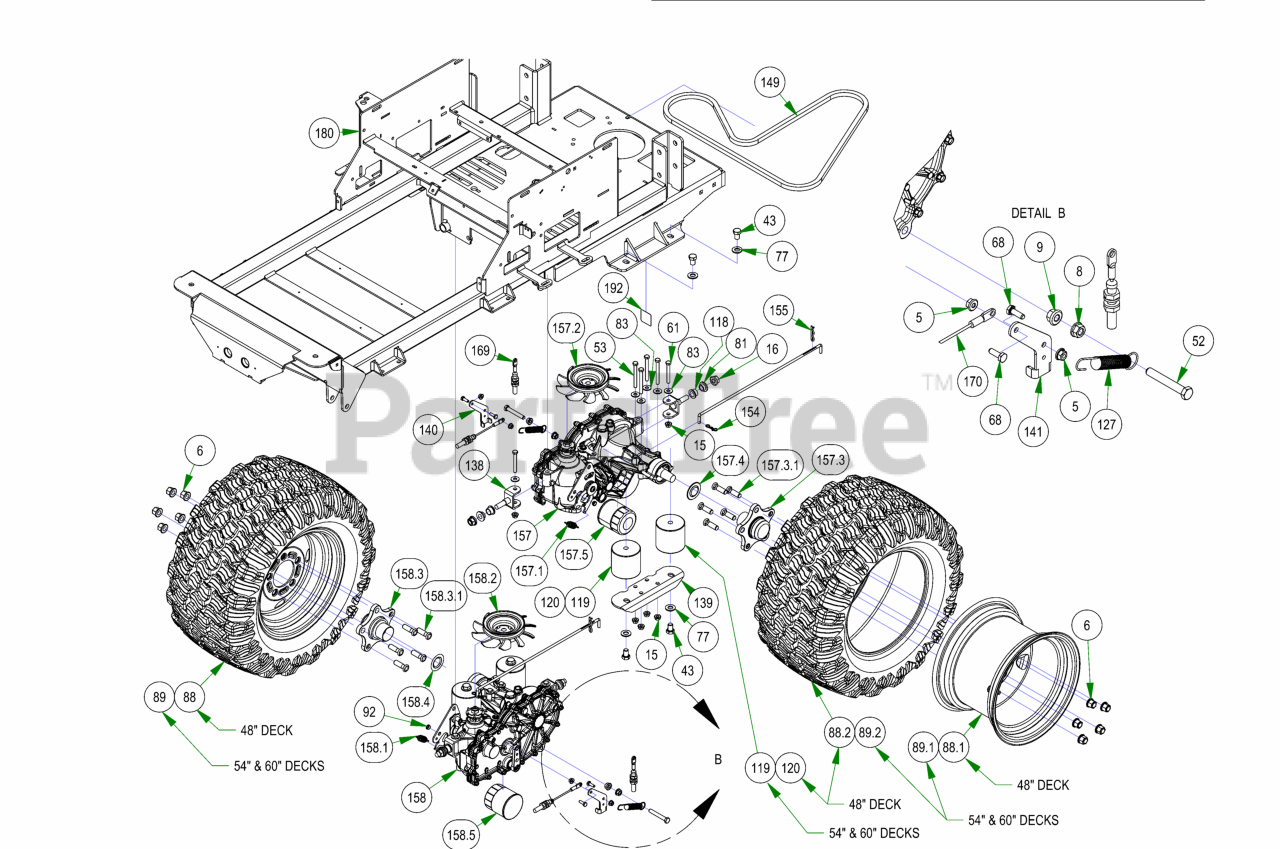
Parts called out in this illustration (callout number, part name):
5	1/4-20 NYL INSERT FLANGE LOCKNUT ZINC
6	Acorn Lug Nut
8	3/8-16 HEX SERRATED FLANGE NUT HARD/ZINC
9	3/8-16 NYLON INSERT FLANGE LOCKNUT (GR.F) ZINC
15	5/16-18 NYLON INSERT FLANGE LOCKNUT ZINC
16	1/2-13 NYLON INSERT FLANGE LOCKNUT ZINC
43	1/2-13 X 3/4 HEX CAP SCREW (GR.5) ZINC
52	3/8-16 X 2-1/2 HEX TAP BOLT (GR.5) ZINC Fully Threaded
53	5/16-18 X 3 HEX CAP SCREW (GR.5) ZINC
61	5/16-18 X 2-1/2 HEX CAP SCREW (GR.5) ZINC
68	1/4-20 X 3/4 HEX CAP SCREW (GR.5) ZINC
77	1/2 SAE FLAT WASHER (1-1/16" OD) GR.8 ZINC YELLOW
81	.525 ID SHOULDER WASHER NYLON
83	5/16 USS FLAT WASHER (7/8 OD) ZINC
88	23x9-12 Reaper Turf Tire & Wheel Assembly
88.1	12x7" Black Wheel
88.2	23x9-12 Reaper Turf Tire Only
89	23x11-12 Reaper Turf Assembly
89.1	12x8.5 Black Wheel
89.2	Tire, 23/11x12 Reaper Turf
92	Drive Arm Transaxle Spacer
105	Neutral Rod
118	.627 ID X .753 OD X .500 LGTH X 1.000 FLG OD X .094 FLG THICK FLANGED BEARING OIL-IMPREG BRNZ
119	Vibration Mount-Green Dot
120	Vibration Mount- Red Dot
127	Brake Return Spring
138	Maverick Rear Transaxle Pivot Bracket
139	Rear Suspension Transaxle Mount
140	Brake Arm Ext (Left)
141	Brake Arm Ext (Right)
149	75.8" Pump Belt
155	Neutral Rod Clip
157	2021 LH 3200 Transaxle
157.1	Gold Transaxle Spring
157.2	2021 ZT/Maverick Transaxle Fan/Pulley Kit
157.3	5 Bolt Hub Kit
157.3.1	Transaxle Wheel Studs/ Drum Brake Studs
157.4	2021 ZT/Maverick Transaxle Seat Kit (ZT-2800)
157.5	ZT Hydraulic Filter
158	2021 RH 3200 Transaxle
158.1	Gold Transaxle Spring
158.2	2021 ZT/Maverick Transaxle Fan/Pulley Kit
158.3	5 Bolt Hub Kit
158.3.1	Transaxle Wheel Studs/ Drum Brake Studs
158.4	2021 ZT/Maverick Transaxle Seat Kit (ZT-2800)
158.5	ZT Hydraulic Filter
169	2021 Load Balanced Brake Cable 1
170	2021 Load Balanced Brake Cable 2
180	2022 Maverick Frame - Painted
192	Patent Decal
